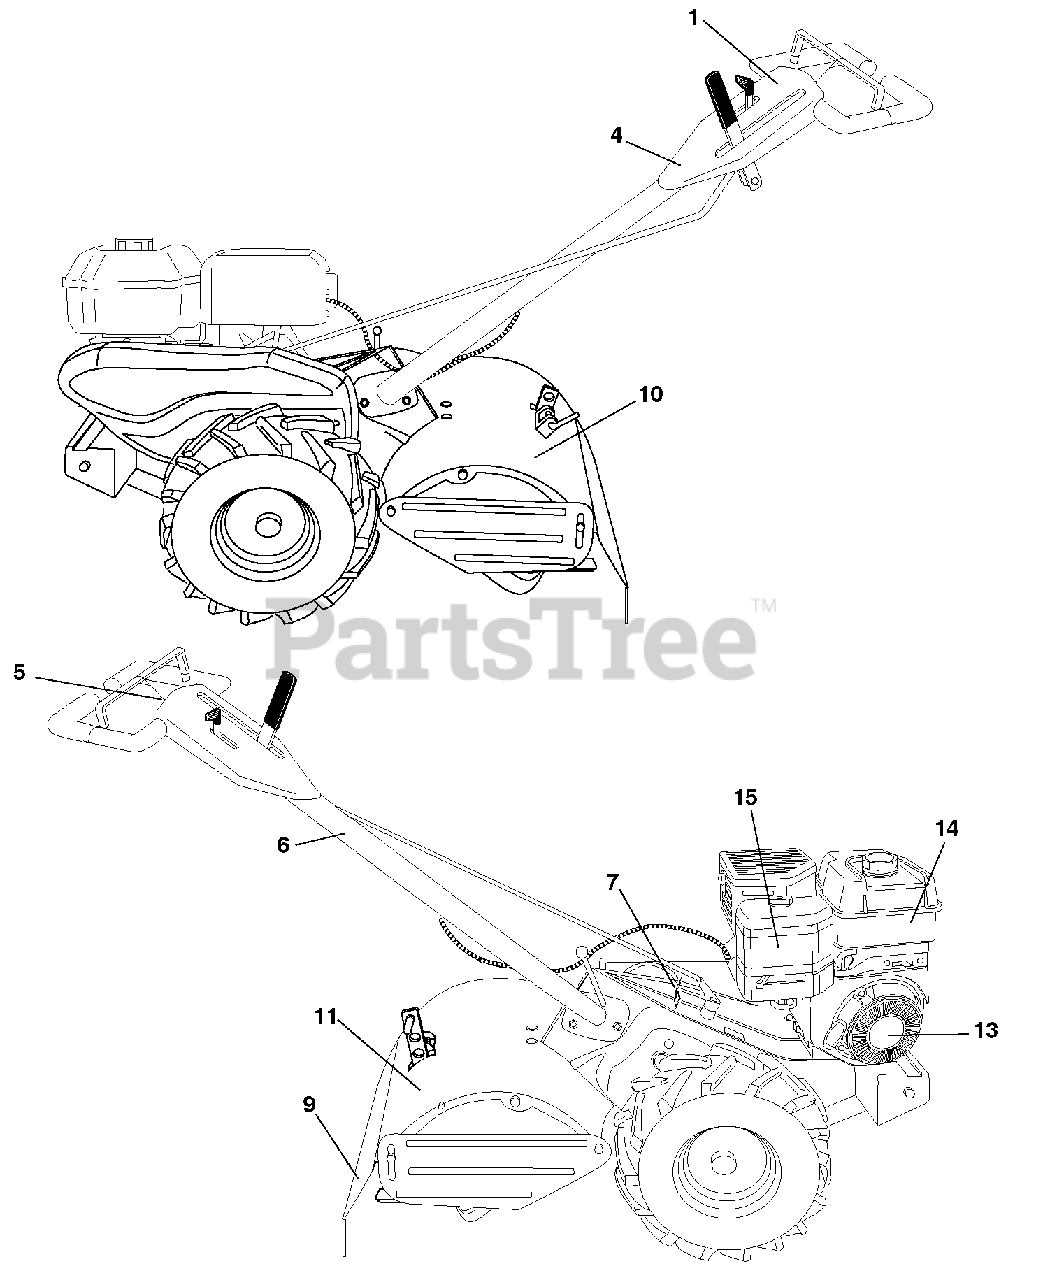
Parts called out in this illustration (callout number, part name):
1	Decal, Service CNTRL PNL
3	Decal, Blt Guard
4	Decal, Control Panel
5	Decal, Caution, Drive Control
6	Decal, Hand Placement
7	Decal, Shift Indicator
8	Decal, Tine, Shield, Counter Rotating Tines
9	Decal, Warning, Rotating Tines
10	Decal, Tine
11	Decal, Tine, Shield, Warning Dom
13	Decal, Rewind
14	Decal, Engine
15	Decal, Intek
15	Manual, Owner's (Eng/Span)
15	Manual, Operator's
